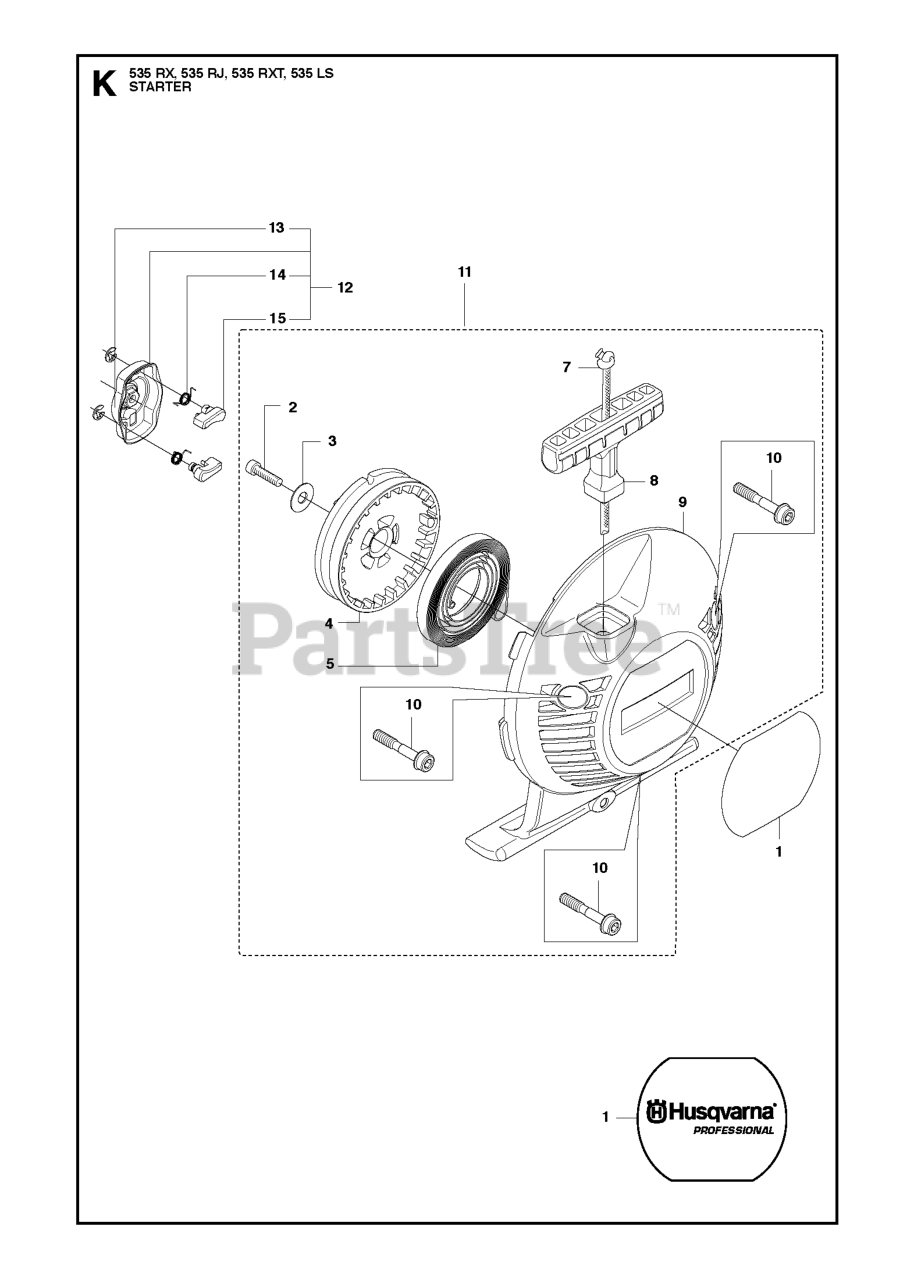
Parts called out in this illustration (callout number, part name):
1	DECAL STARTER 535/135/336 "PRO
4	%STARTER PULLEY
5	STARTER SPRING
7	STARTER ROPE
8	STARTER HANDLE
9	STARTER
10	SCREW IHSCFMO
11	STARTER ASSY
12	STARTER PAWL BRIDGE
15	STARTER PAWL
